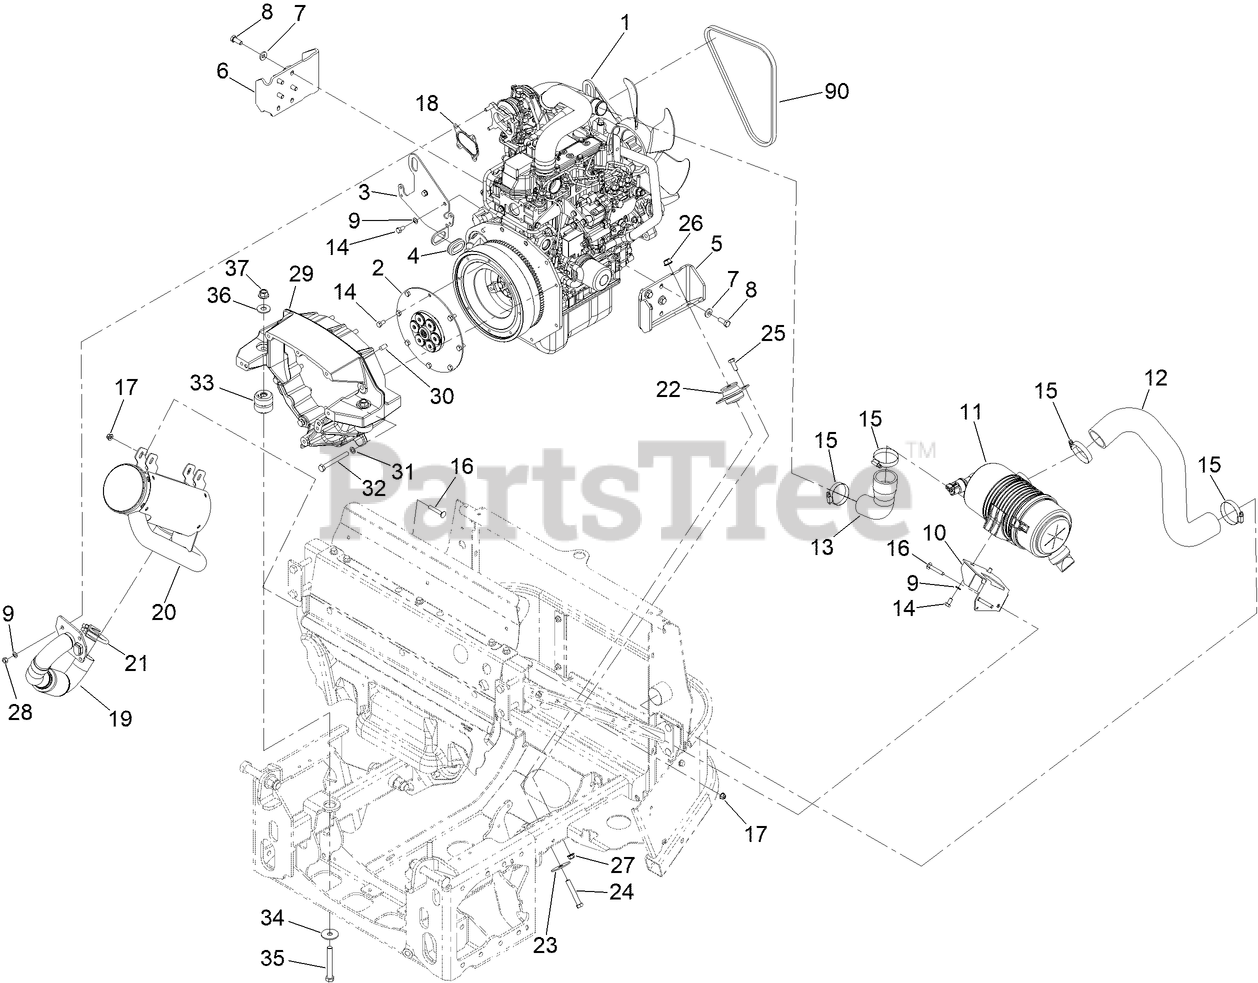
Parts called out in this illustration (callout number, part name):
1	ENGINE-YANMAR, 3TNV80FT-ZMTR1
2	COUPLER-FLYWHEEL
3	BRACKET-GUIDE
4	GROMMET
5	MOUNT-ENGINE, LH
6	MOUNT-ENGINE, RH
7	WASHER-BELLEVILLE
8	SCREW-HH
9	WASHER-BELLEVILLE
10	BRACKET-CLEANER, AIR
11	ASM, HDAC
12	HOSE-AIR
13	HOSE-AIR
14	BOLT
15	CLAMP-HOSE
16	BOLT-CARR
17	NUT-HF, NI
18	GASKET-HEADER
19	HEADER PIPE
20	MUFFLER
21	CLAMP
22	MOUNT- ISOLATOR, ENGINE
23	WASHER-SNUBBING
24	SCREW-HH
25	SCREW-HH
26	NUT-HF, NI
27	NUT-HF, NI
28	NUT-HEX
29	HOUSING-FLYWHEEL
30	PIN-DOWEL
31	WASHER-LOCK
32	SCREW-HH
33	MOUNT-ISOLATOR
34	WASHER-THRUST
35	SCREW-HH
36	WASHER-FLAT
37	NUT-LOCK
90	V-BELT
